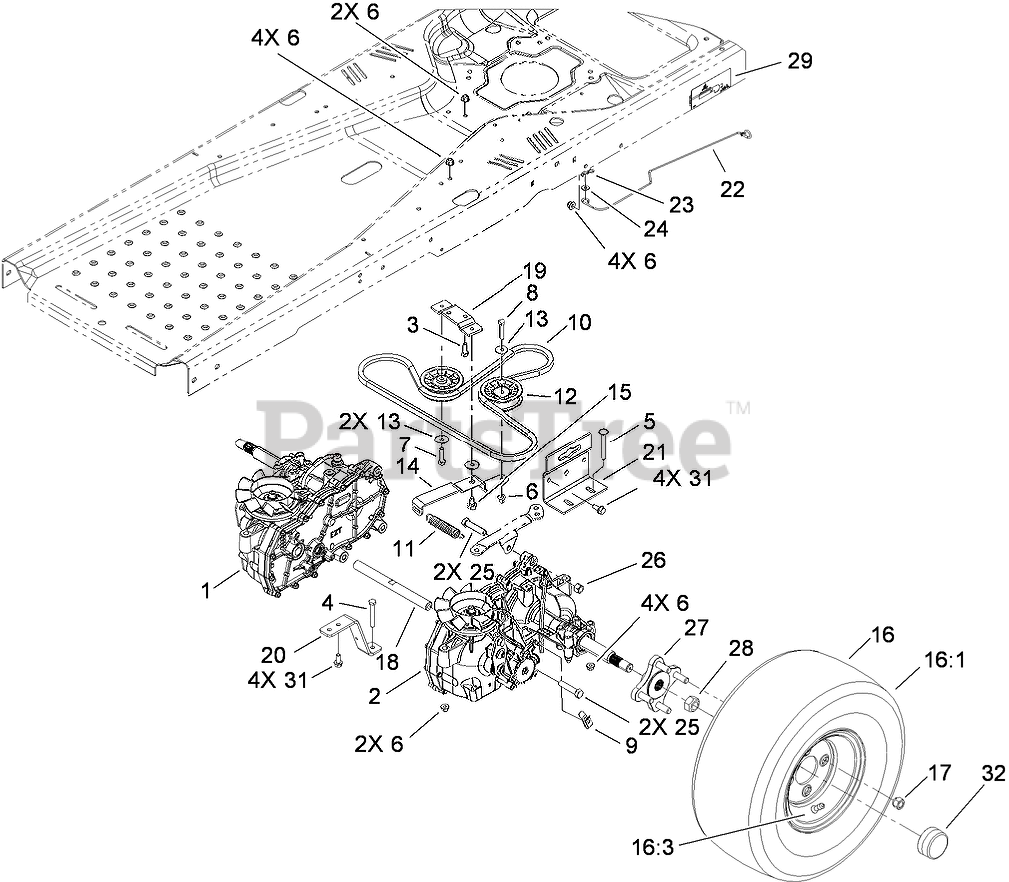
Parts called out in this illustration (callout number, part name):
1	HYDRO-RH
2	HYDRO-LH
3	SCREW-HH
4	SCREW-HH
5	SCREW-CARR
6	NUT-HF, NI
7	SCREW-HH
8	SCREW-HH
9	CLIP-SPRING
10	V-BELT
11	SPRING-IDLER
12	PULLEY-IDLER
13	WASHER-PIVOT
14	ARM-IDLER
15	BOLT-SHOULDER
16	WHEEL AND TIRE ASM
16:3	STEM-VALVE
17	NUT-LUG
18	SHAFT-CROSS
19	PLATE-PIVOT
20	STRAP-TORQUE
21	SUPPORT-HYDRO
22	ROD-BYPASS
23	PIN-COTTER
24	WASHER-FLAT
25	SCREW-HH
26	NUT-LOCK, NI
27	HUB ASM
28	NUT-LOCK
29	DECAL-TRANSPORT, LH
31	SCREW-HHF
32	COVER-NUT, AXLE
